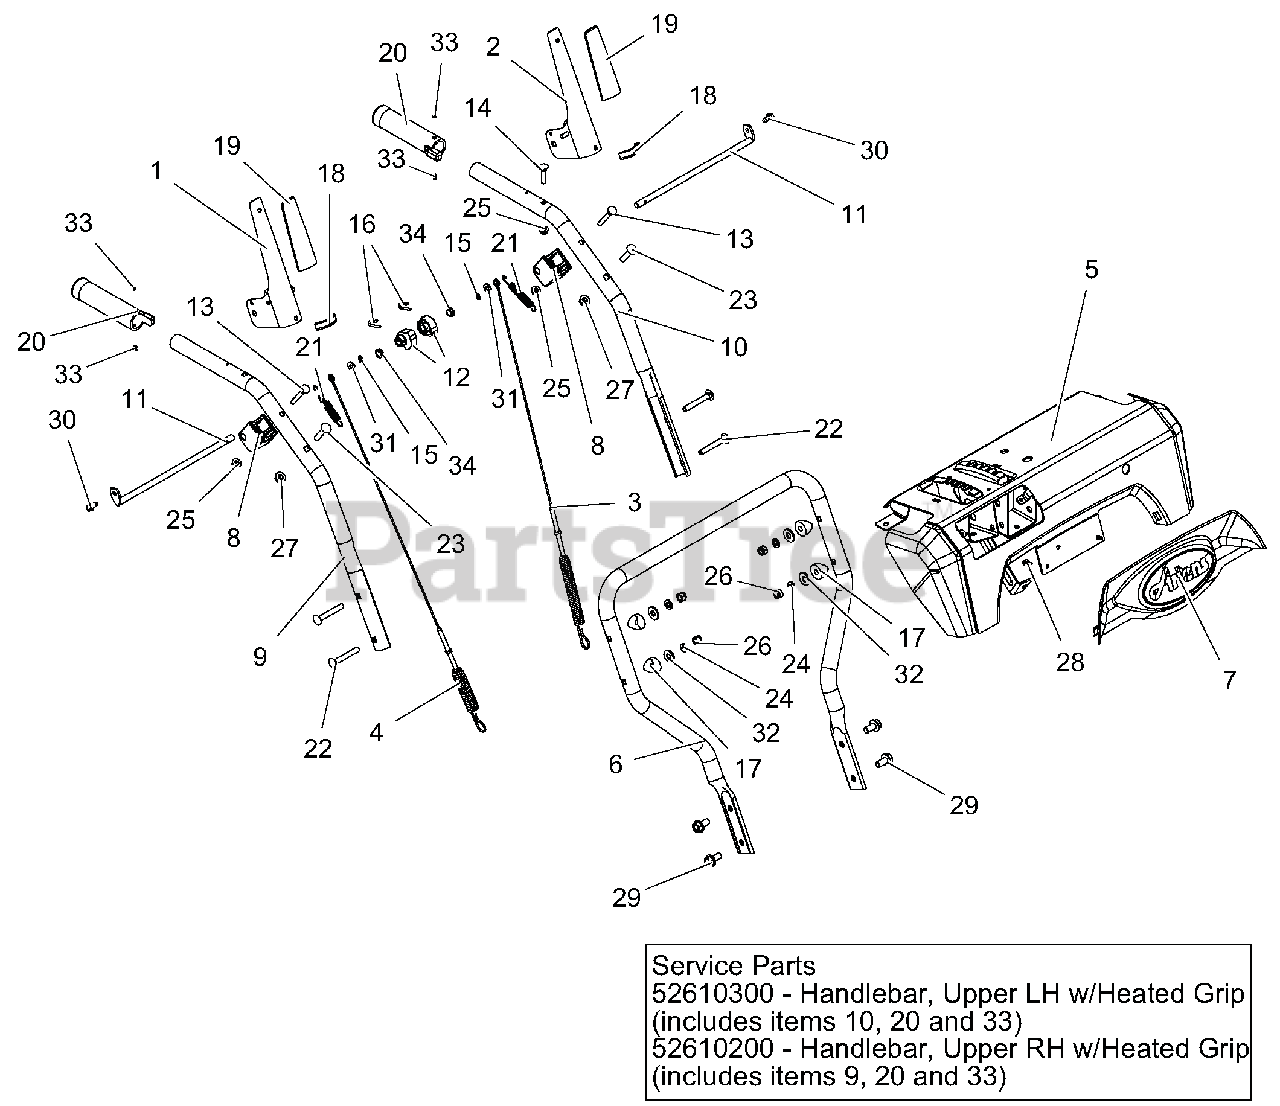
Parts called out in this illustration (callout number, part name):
1	LEVER, CLUTCH-RH
2	LEVER, CLUTCH-LH
3	CABLE, UPPER TRACTION
4	CABLE, AUGER (DELUXE & PRO)
5	CTRL PANEL W/DECAL, CRNK TK HW
6	HANDLEBAR, LOWER - DELUXE
7	DASH BEZEL, ARIENS LOGO - PRO
8	BLOCK, CLUTCH PADDLE
9	HANDLEBAR, UPPER - RH
10	HANDLEBAR, UPPER - LH
11	ROD, PADDLE MOUNT - PRO
12	CAM, INTERLOCK
13	BLT-RDHDXLSQNK .25-20X2.0 G5YZ
14	BLT-RDHDXLSQNK.25-20X1.25 G5ZC
15	PIN-HAIR INT .06X.18X.77
16	PIN, SPRING CLIP
17	SPACER, HANDLEBAR
18	EDGING, CLUTCH PADDLE - 2.00"
19	CLUTCH PADDLE SLEEVE - GRAY
20	HEATED GRIP, MAGURA
21	SPRING, EXTENSION
22	@BLT-RDHDSQNK .31-18X2.25 G5YZ
23	@BLT-RDHDSQNK .31-18X1.50 G5YZ
24	WSHR-LK .312X.097 HVY YWZC
25	@NUT-LK-CTR-FLG .25-20 YWZC
26	@NUT-LK-NYL .312-18 YWZC
27	@NUT-LK-TOP-FLG .31-18 YWZC
28	SCR-TAP #10X.50 BOSS INDHXHD
29	BLT-SERHFWH .38-16X.75 YWZC
30	SCR-TAP .25-20X.50 HWH TR YWZ
31	@WSHR-FL-STL.281X.62X.065 YWZC
32	@WSHR-FL-STL.38X.875X.083 YWZC
33	RVT-POP #43 .125X.313 STL ZINC
34	BUSHING, POLYLINER-.38 SNAPIN
